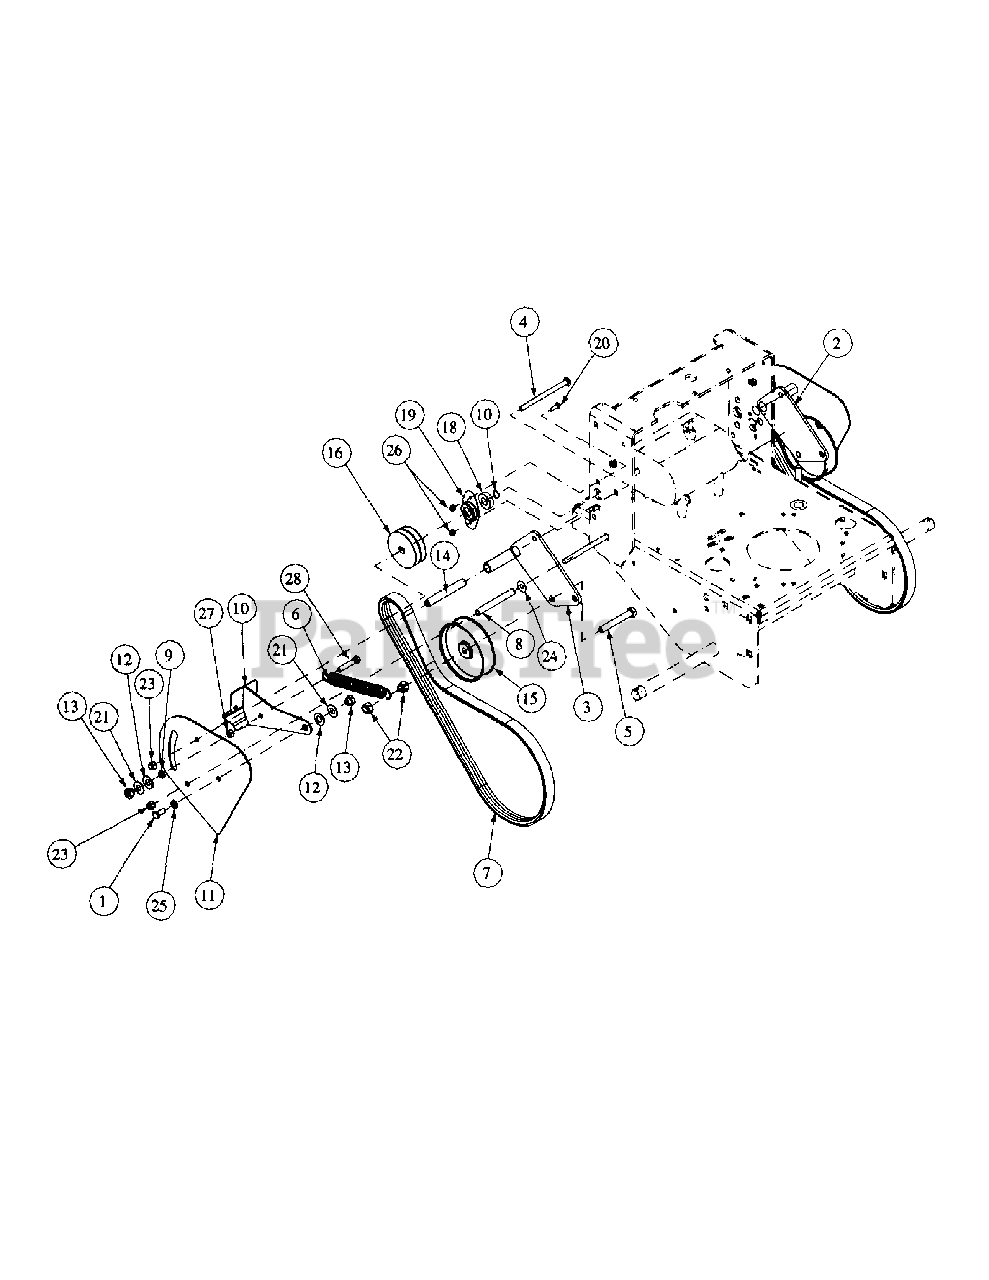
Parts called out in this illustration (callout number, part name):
1	Hex Cap Screw, 3/8-16, .875
2	Left Idler Bracket
3	Right Idler Bracket
4	Carriage Bolt, 3/8-16 x 5.50
5	Hex Cap Screw, 1/2-13, 3.50
6	Extension Spring
7	Belt, V
8	Spacer Tube
9	Roller Tube
10	Spring Adjust
11	Belt Guard
12	Slide Washer
13	Shoulder Nut
14	Idler Sleeve
15	Flat Idler Drive
16	Jackshaft Pulley
17	External Retain Ring
18	Bearing
19	Bearing Housing
20	Carriage Bolt, 1/4-20 x .750
21	Washer, 1/2 x 1
22	Lock Nut, Nylon Insert, 1/2-13
23	Lock Nut, Nylon Insert, 3/8-16
24	Flat Washer, 3/8 Zinc
25	Lock Washer, 3/8 Zinc
26	Lock Nut, Nylon Insert, 1/4-20
27	Hex Nut, 3/8-16
28	Hex Cap Screw, 3/8-16, 2.00
